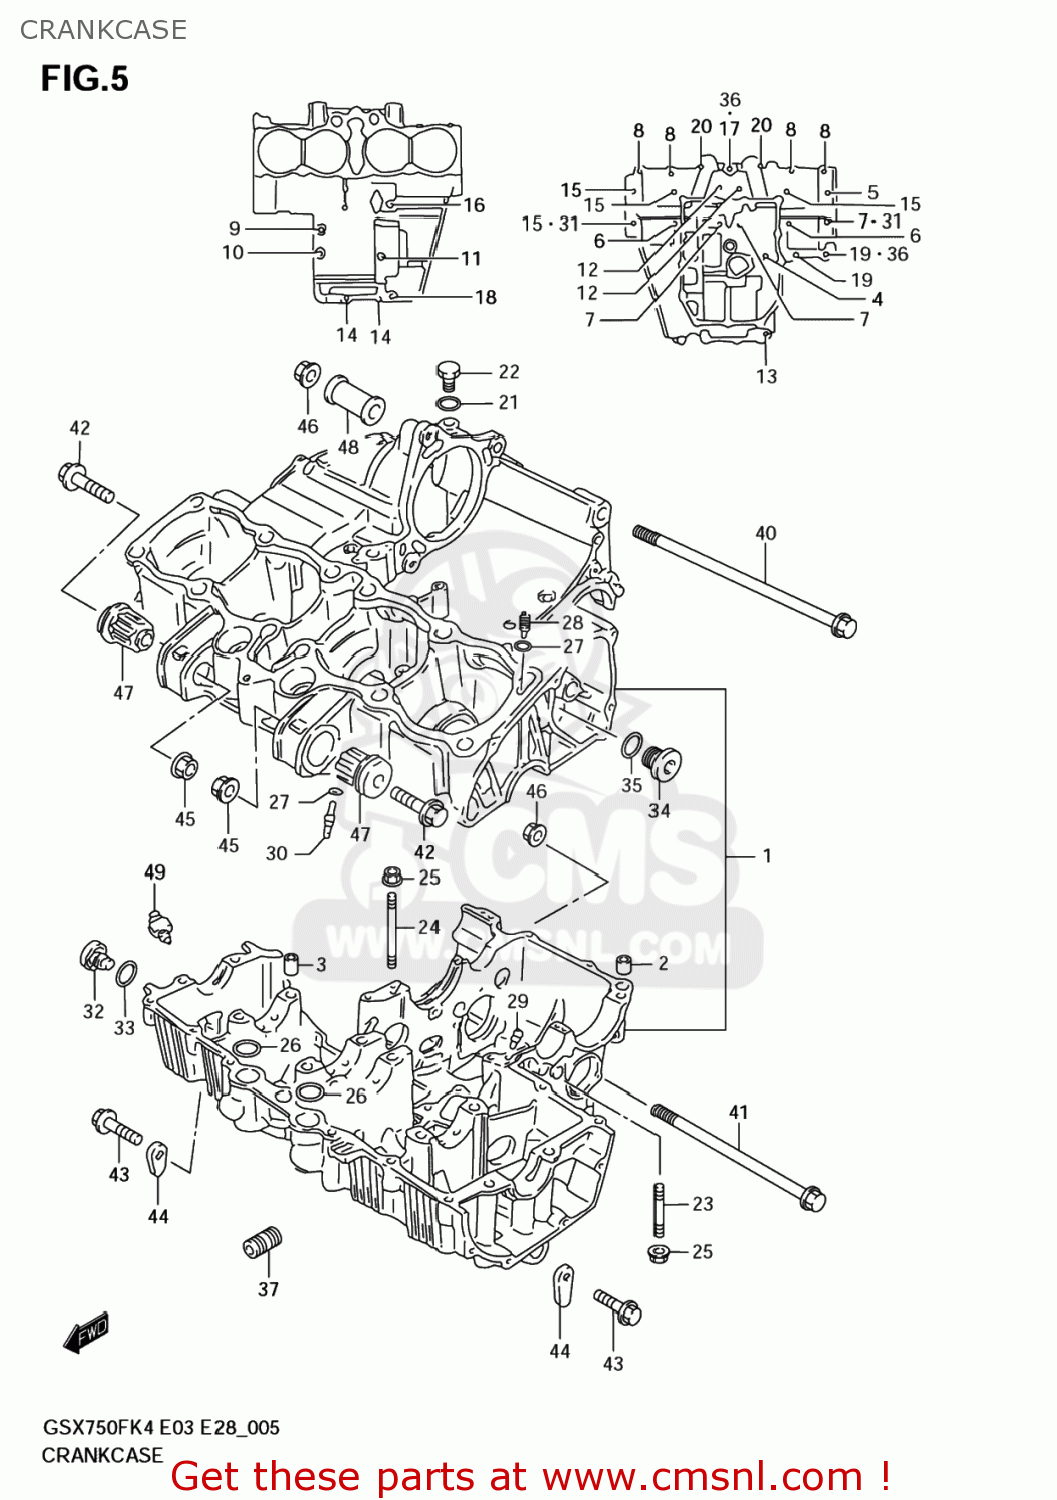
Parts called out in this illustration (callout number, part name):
1	CRANKCASE SET
2	PIN(10.4X13X22)
3	PIN(8.4X11X20)
4	BOLT(6X105)
5	BOLT(8X105)
6	BOLT(8X125)
7	BOLT(8X115)
8	BOLT
9	BOLT
10	BOLT,CL.COVER
11	BOLT
12	BOLT
13	BOLT
14	BOLT
15	BOLT(8X95)
16	BOLT
17	BOLT
18	BOLT
19	BOLT, HYDRAULIC UNIT NO.2
20	BOLT
21	GASKET(12.1X16.2X3.7) (NAS)
22	PLUG(12X9)
23	STUD BOLT
24	STUD BOLT
25	NUT
26	O RING(D:2.5,ID:21)
27	O RING(D:1.2,ID:4)
28	JET,AIR
29	JET
30	JET(13)
31	GASKET(8.5X17X2.3) (NAS)
32	PLUG
33	O RING(D:2.4,ID:16.8)
34	PLUG
35	GASKET(13.8X18.8X4.8) (NAS)
36	GASKET(5.8X13X1.2) (NAS)
37	UNION,OIL STAND
38	PLATE,CRANK THRUST
39	PLATE,CRANK THRUST
40	BOLT(10X175)
41	BOLT(10X130)
42	BOLT
43	BOLT(10X50)
44	NUT
45	NUT
46	NUT
47	BUSH,ENGINE MOUNTING
48	SPACER,ENGINE MOUNT(L27)
49	SWITCH ASSY,OIL PRESSURE
